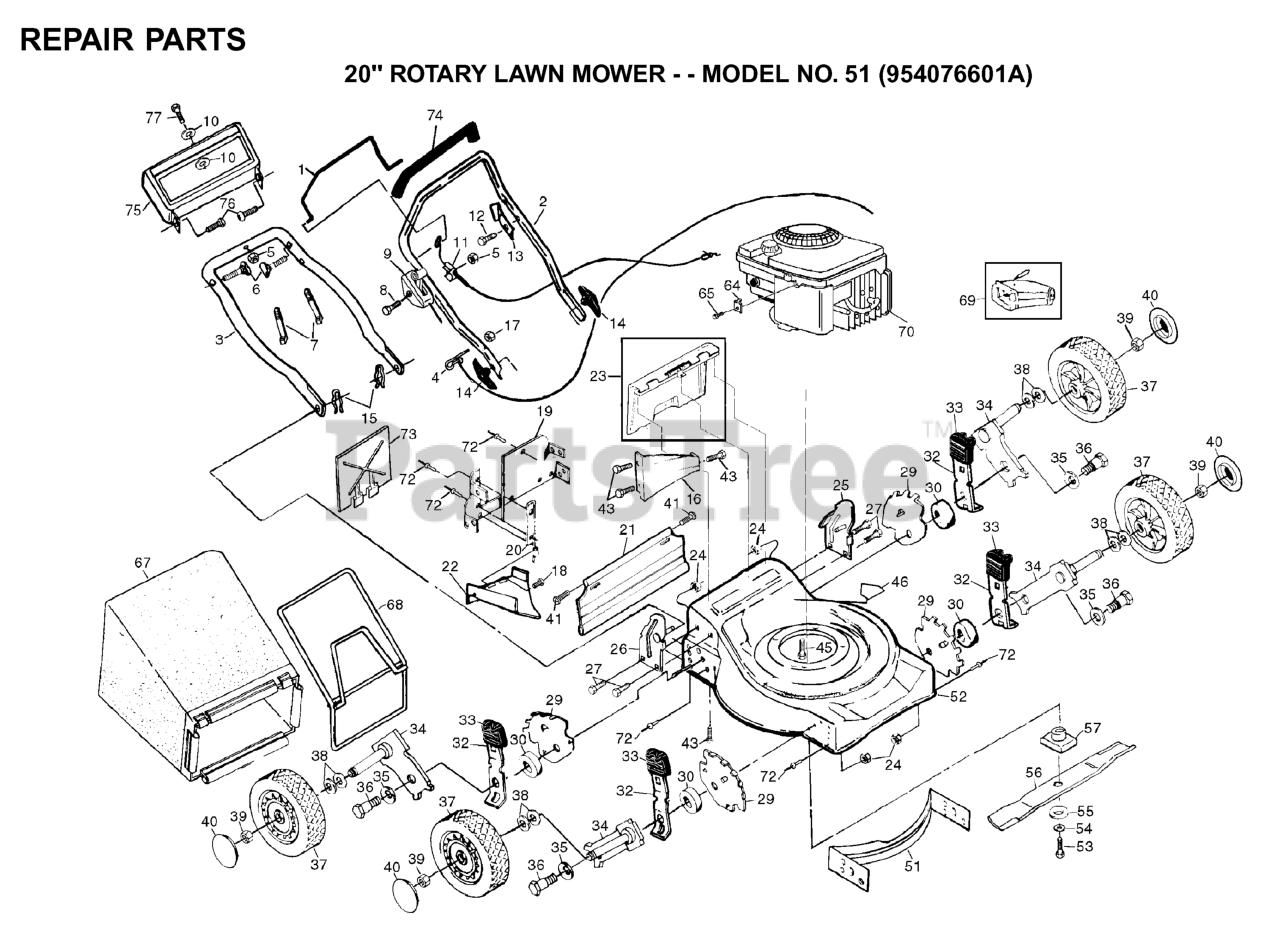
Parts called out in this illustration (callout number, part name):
1	CONTROL BAR/BLACK
2	UPPER HANDLE
3	HANDLE, LOWER PM
4	ROPE GUIDE
5	NUT
6	HANDLE BOLT
7	TIE GUIDE
8	SCREW 1/4-20 X 2.12
9	THROTTLE CONTROL
11	CABLE.MZR.51.RT.SP./PU.
12	TAPPING SCREW
13	BRACKET UPSTOP
14	HANDLE KNOB
15	HAIRPIN COTTER
16	REAR BAFFLE
17	NUT
18	SCREW.HXTAP.10-24
19	BACK PLATE
20	SIDE BAFFLE
21	REAR SKIRT
22	DISCHARGE BAFFLE
23	REAR DOOR KIT
24	LOCKNUT PM
27	SELF-TAPPING SCREW 5/16-18X3/4
29	WHEEL ADJUST BRACKET
30	RP SPACER HT ADJ
32	SELECTOR SPRING
33	SELECTOR KNOB
34	AXLE, REAR
35	WASHER.BELLEVILLE (3 2 LB)
36	BOLT
37	WHL & TIRE ASSEMBLY
38	WAVE WASHER
39	HEX FLANGE LOCKNT
41	HINGE SCREW
45	BOLT 3/8-16X1-1/8
46	DECAL HYT
51	FRONT BAFFLE
52	HOUSING ASSY
53	SCREW, HEX HD 3/8-24 X 1-3/8
54	LOCKWASHER
55	WASHER,HARDEN
56	BLADE 20" MULCH
57	BLADE ADAPTOR
65	SCREW.HEX.HEAD.WASHER.10-16
67	GRASS BAG
68	CATCHER.FRAME.WALK
72	RIVET BLIND
74	HANDLE GRIP
75	TRIM PLATE
77	SCREW
